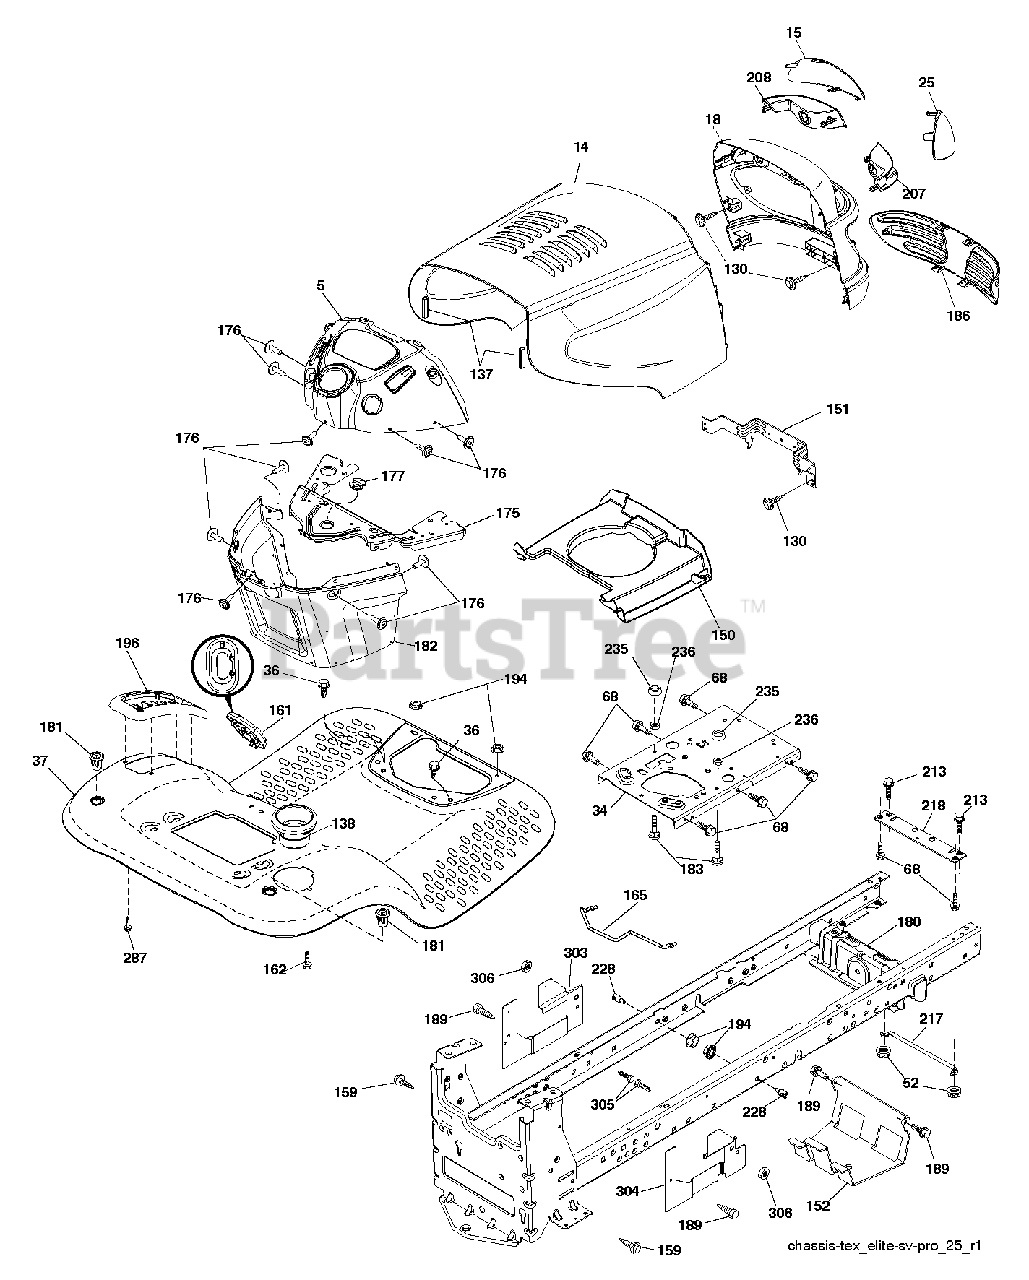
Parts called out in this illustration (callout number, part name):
34	PLATE.ENGINE.WELDED.CHASSIS
36	SCREW 3/8-16X3/4
52	LOCKNUT
130	SCREW.#10 X 0.750.BOS THREAD
137	BUMPER.HOOD.LARGE.1.75"
138	CUPHOLDER.TL.TEX.BLACK
151	BRACKET PIVOT
152	SHIELD BROWNING
159	SCREW, 3/8-16X3/4
161	RP WINDOW.FUEL.LT.TEX.GREY
162	SCREW.HI-LO.CONSOLE
165	SUPPORT.TANK.REAR.W/TE
175	CROSSMEMBER.LT
176	SCREW.#10-24X5/8.RN.QU
177	BUSHING STEERING
180	CHASSIS
181	FEND/FTRST.PCH.CPH.NFW
182	DASH.LOWER.LT.CCS
183	BOLT.5/16-18X1-1/4 FULL THD
189	SCREW
194	NUT LOCK HEX FLANGE 5/16-18
196	CONSOLE.ASM.DECKLFT.BL/RBT.TLT
207	BEZEL GRILL RH
208	BEZEL GRILL LH
213	BOLT
217	ROD.PIVOT.HOOD
218	X-PIECE.HOOD.STOP.NON/
228	STUD.FASTNER.W/ANTI-ROTATE
235	SPACER FENDER
236	NUT.CENTERLOCK.5/16-
306	NUT LOCK FLG 3/8-16 UNC
